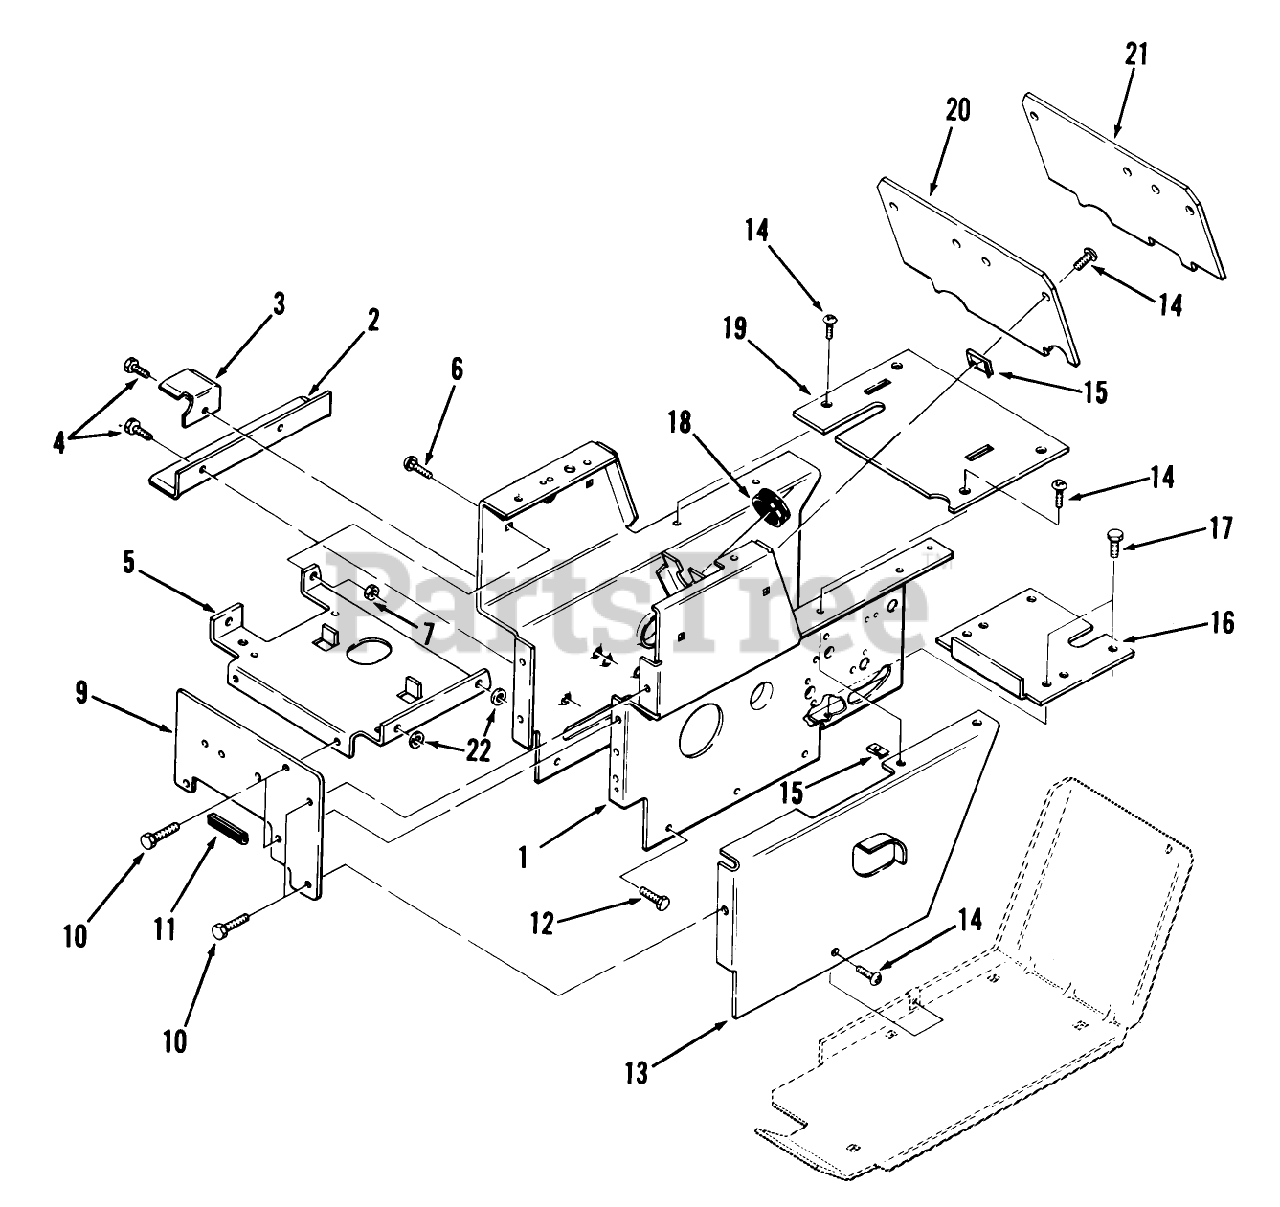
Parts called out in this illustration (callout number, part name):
2	ANGL-BLT GURD*B
3	BRCKET-BLT SUT*B
4	SCREW
10	SCREW
12	SCREW
17	SCREW
18	GROMMET
19	Shift Cover Plate
22	WASHER 5/16 SAE
